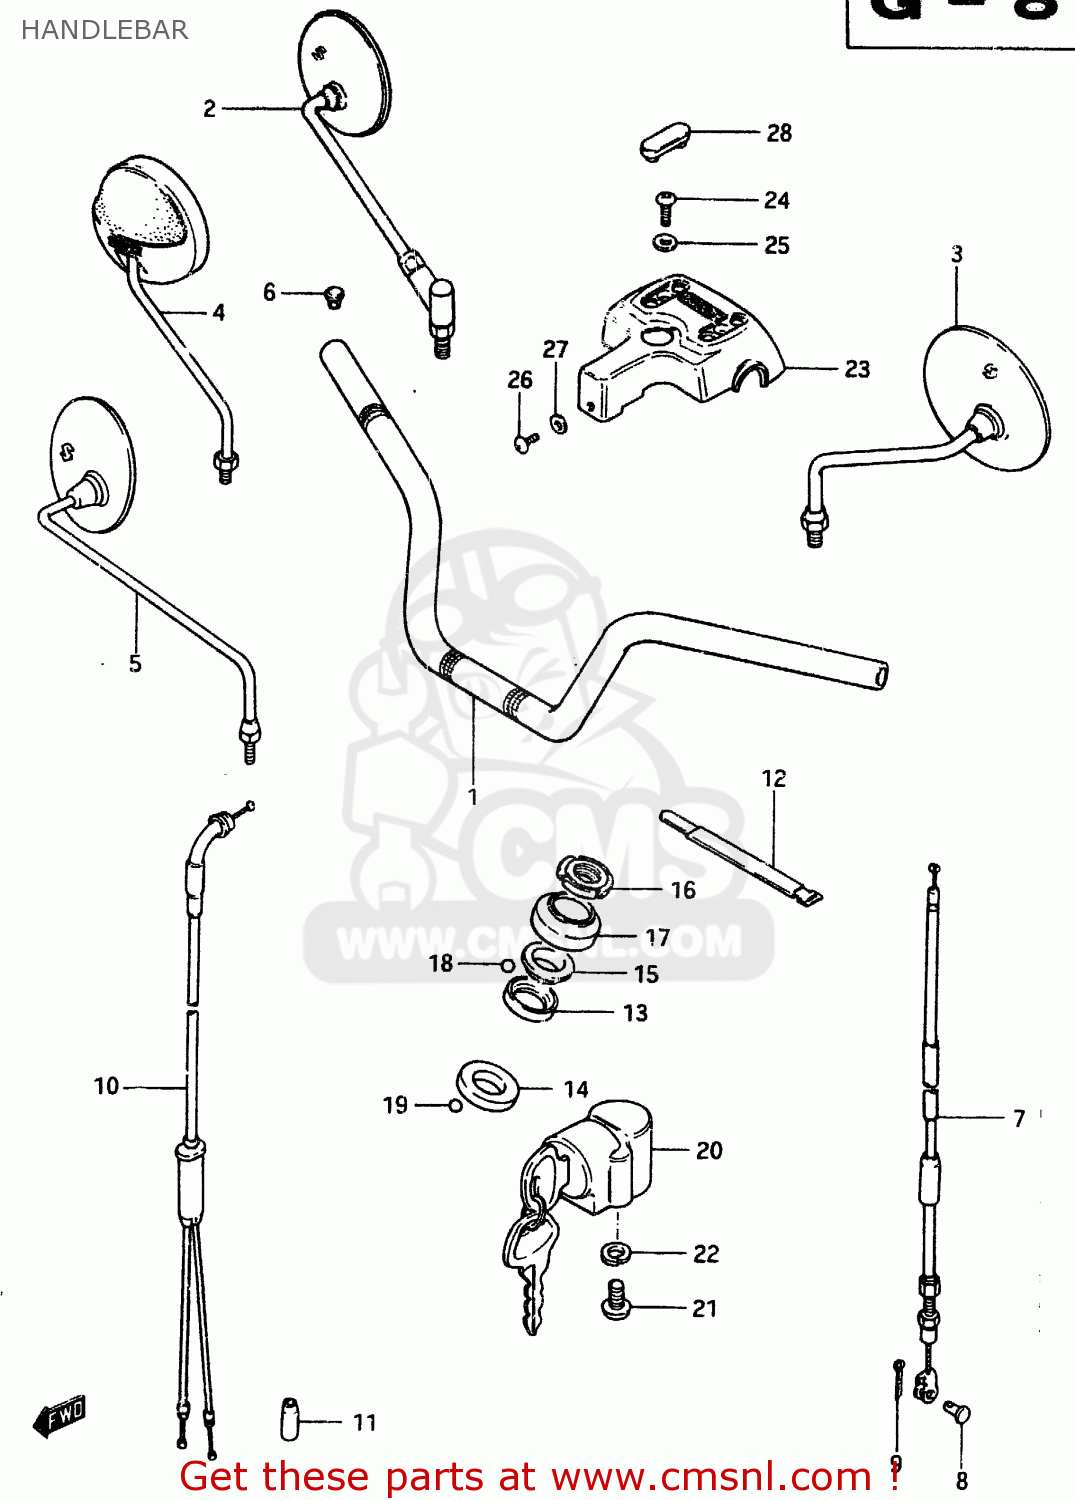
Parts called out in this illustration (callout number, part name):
1	HANDLEBAR
2	MIRROR ASSY, REAR VIEW
3	MIRROR, REAR VIEW LH
4	MIRROR ASSY, REAR VIEW
5	MIRROR ASSEMBLY,LEFT
6	CAP
7	CABLE ASSY,CLUTCH
8	PIN(L:13)
9	PIN
10	CABLE, THROTTLE
11	SEAL,DUST(7X18X30)
12	CLAMP
13	RACE,STEERING INNER UPR
14	LACE,STEERING INNER LWR
15	RACE,STEERING OUTER UPR
16	NUT,STEERING STEM(25X44X10)
17	DUST SEAL,STEERING UPR
18	BALL
19	BALL
20	LOCK ASSY,STEERING
21	SCREW
22	LOCK WASHER
23	COVER, STEERING HEAD
24	SCREW 6X12
25	WASHER
26	SCREW
27	WASHER
28	CAP,PILOT LAMP BOLT
